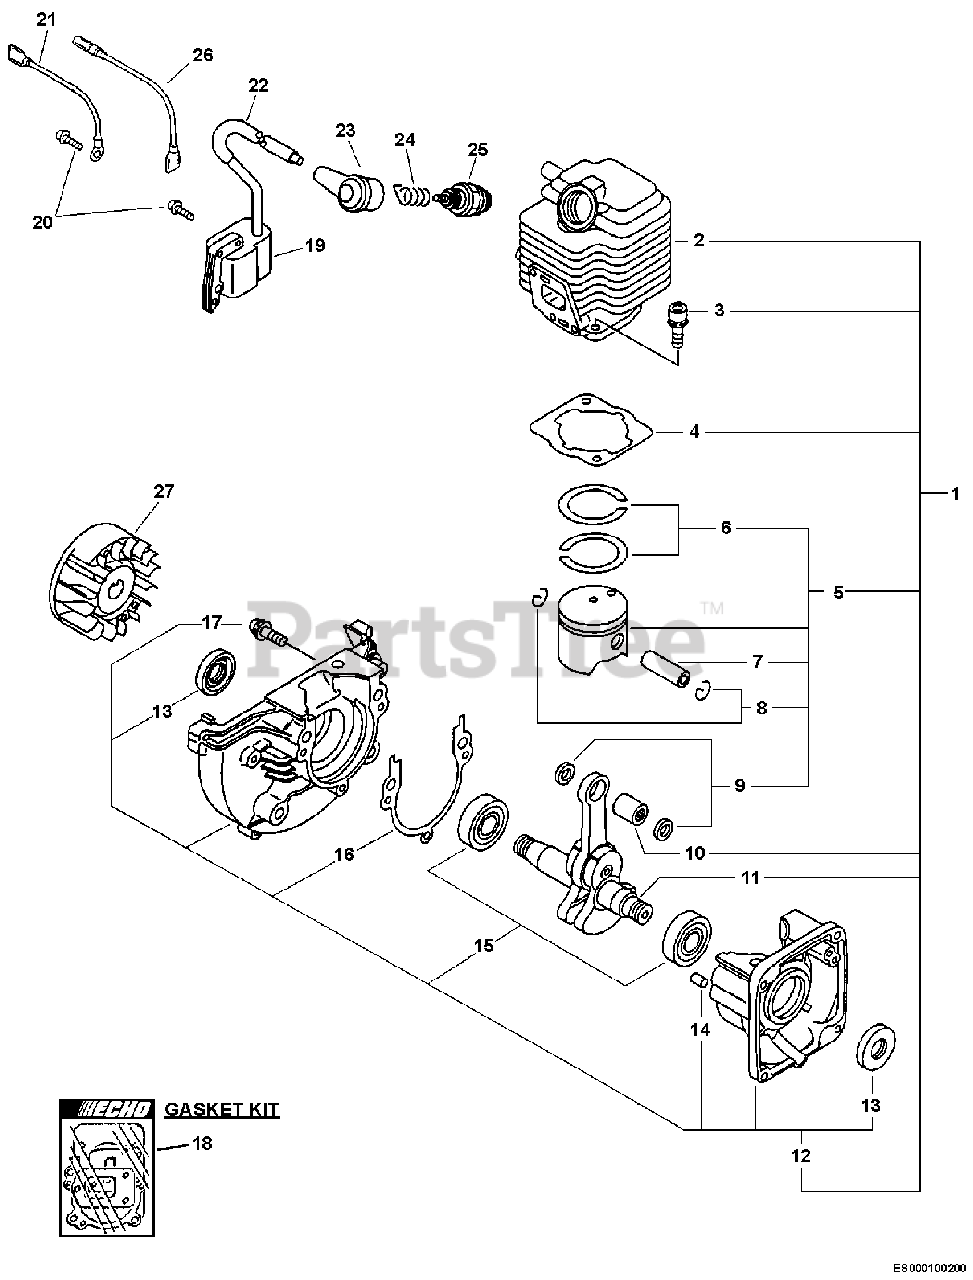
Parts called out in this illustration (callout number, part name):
1	SHORT BLOCK -- SB1049
2	CYLINDER
3	SCREW - 5X22
4	GASKET, CYLINDER
5	PISTON KIT
6	RING, PISTON
7	PIN, PISTON
8	RING, RETAINING
9	SPACER, PISTON
10	BEARING, NEEDLE
11	CRANKSHAFT ASSY
12	CRANKCASE KIT
13	SEAL, OIL
14	PIN - LOCATING
15	BEARING, BALL - 6201
16	GASKET, CRANKCASE
17	SCREW - 5X28
18	GASKET KIT
19	COIL, IGNITION
20	SCREW - 4X22
21	LEAD - IGNITION
23	CAP, SPARK PLUG
24	TERMINAL, SPARK PLUG CAP
25	SPARK PLUG -- BPM-7Y
26	LEAD - GROUND
27	FLYWHEEL
